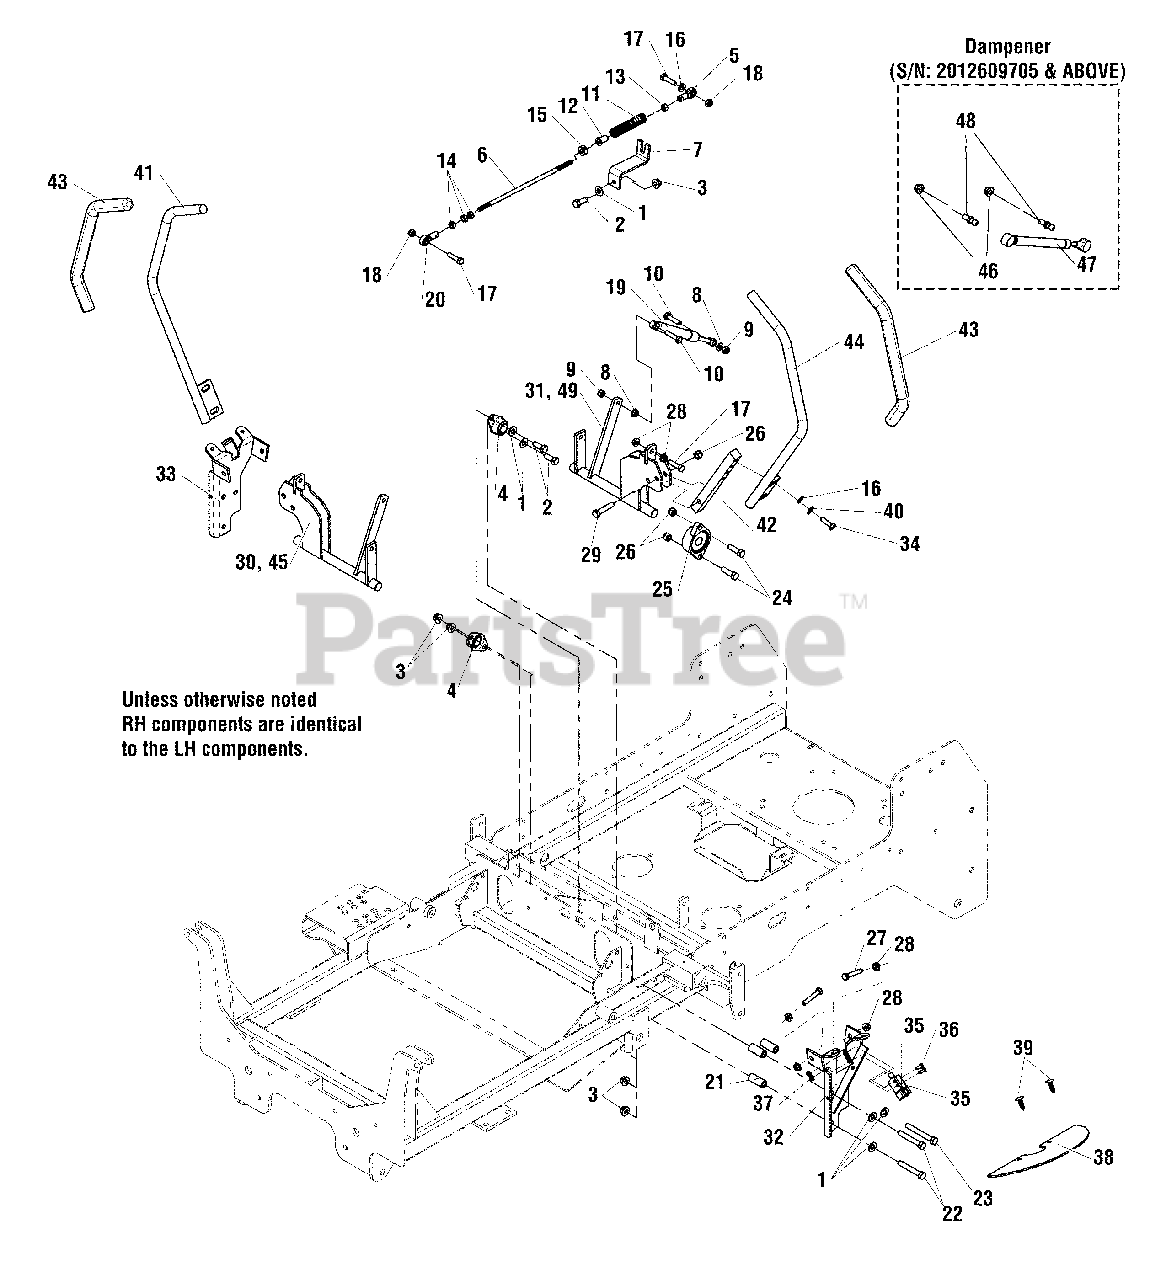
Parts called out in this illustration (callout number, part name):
1	WASHER 3/8" SAE
2	BOLT, 3/8-16 X 1" GD5
3	NUT, 3/8-16 HEX NYLOCK FLANGE
4	BEARING, BRONZE FLANGE 3/4"
5	BALL JOINT 5/16-24 LH FEMALE BRONZE RACE
6	ROD, HYDRO LINKAGE
7	MOUNT, REVERSE RETURN - BLK
8	NUT, M8-1.25 Hex Serrated Flange
9	NUT, M8-1.25 Hex Nylon Lock
10	BOLT, M8-1.25 x 35MM
11	SPRING, COMPRESSION
12	BUSHING, FLANGE 3/8ID X 7/8 LONG
13	NUT, 5/16 HEX LH
14	NUT, HEX 5/16-24
15	SET COLLAR, 5/16"
16	WASHER, 5/16" SAE
17	BOLT, 5/16-18 X 1-1/4" GD5
18	NUT 5/16-18 HEX NYLON LOCK
19	DAMPENER
20	BALL JOINT 5/16-24 RH FEMALE BRONZE RACE
21	SPACER, .63 X .39 X 1.50
22	BOLT, 3/8-16 X 2-1/2" GD5
23	BOLT, 3/8-16 X 3" GD5
24	BOLT, 3/8-16 X 1-1/4" GD5
25	BEARING, FLANGE
26	NUT, 3/8-16 HEX NYLON LOCK
27	BOLT, 5/16-18 X 1-3/4" GD5
28	NUT, 5/16-18 HEX SM. SERR. FLG.
29	BOLT, 3/8-16 X 1-3/4" GD5
30	WELD, CONTROL SHAFT, RH - ORANGE
31	WELD, CONTROL SHAFT, LH - ORANGE
32	WELD, NEUTRAL LOCK, LH - BLK
33	WELD, NEUTRAL LOCK, RH - BLK
34	BOLT, 5/16-18 X 1" GD5
35	SWITCH, PLUNGER, N.O./N.C.
36	10-24 X .5 SCREW
37	NUT, HEX, #10-24
38	GUARD, RUBBER MOTION CONTROLS
39	PUSH RIVET (TREE TYPE) BLACK
40	WASHER, 5/16" LOCK
41	WELD, HANDLE MOTION CONTROL, RH - BLK
42	MOUNT, CONTROL ARM - BLK
43	GRIP, FOAM, 3/4" ID, 16" LONG
44	WELD, HANDLE MOTION CONTROL-LH - BLK
45	WELD, CONTROL SHAFT, RH - BLK
46	NUT, 5/16-18 HEX NYLON FLANGE
47	DAMPENER, CONTROL
48	BALL STUD, 10MM, 5/16-18 X 3/4
49	WELD, CONTROL SHAFT, LH - BLK
